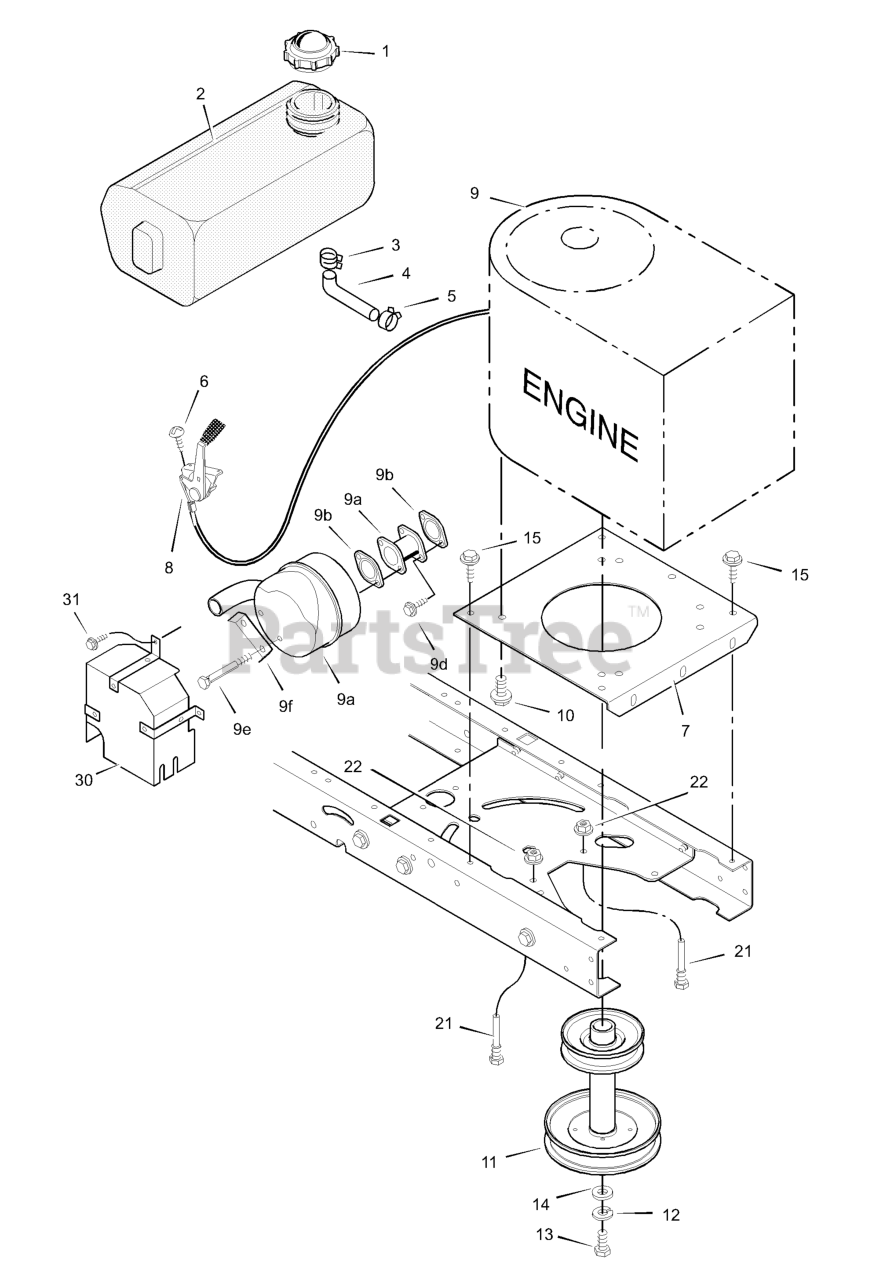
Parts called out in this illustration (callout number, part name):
1	Fuel Cap
2	Fuel Tank
3	Hose Clamp
4	Fuel Line (Must cut to length)
5	Hose Clamp
7	Plate, Engine
8	Throttle Control
9	Engine
9A	Muffler
9B	GASKET, Exhaust
9C	Adapter, Muffler
9D	Screw, Adapter
9E	Bolt, Muffler
9F	Lock, Screw
10	Bolt, Engine Mount
11	STACK PULLEY ASSEMBLY
12	Lockwasher
13	Bolt, Hex
21	Guide, Belt
22	Nut, Flange
30	Shield, Heat
